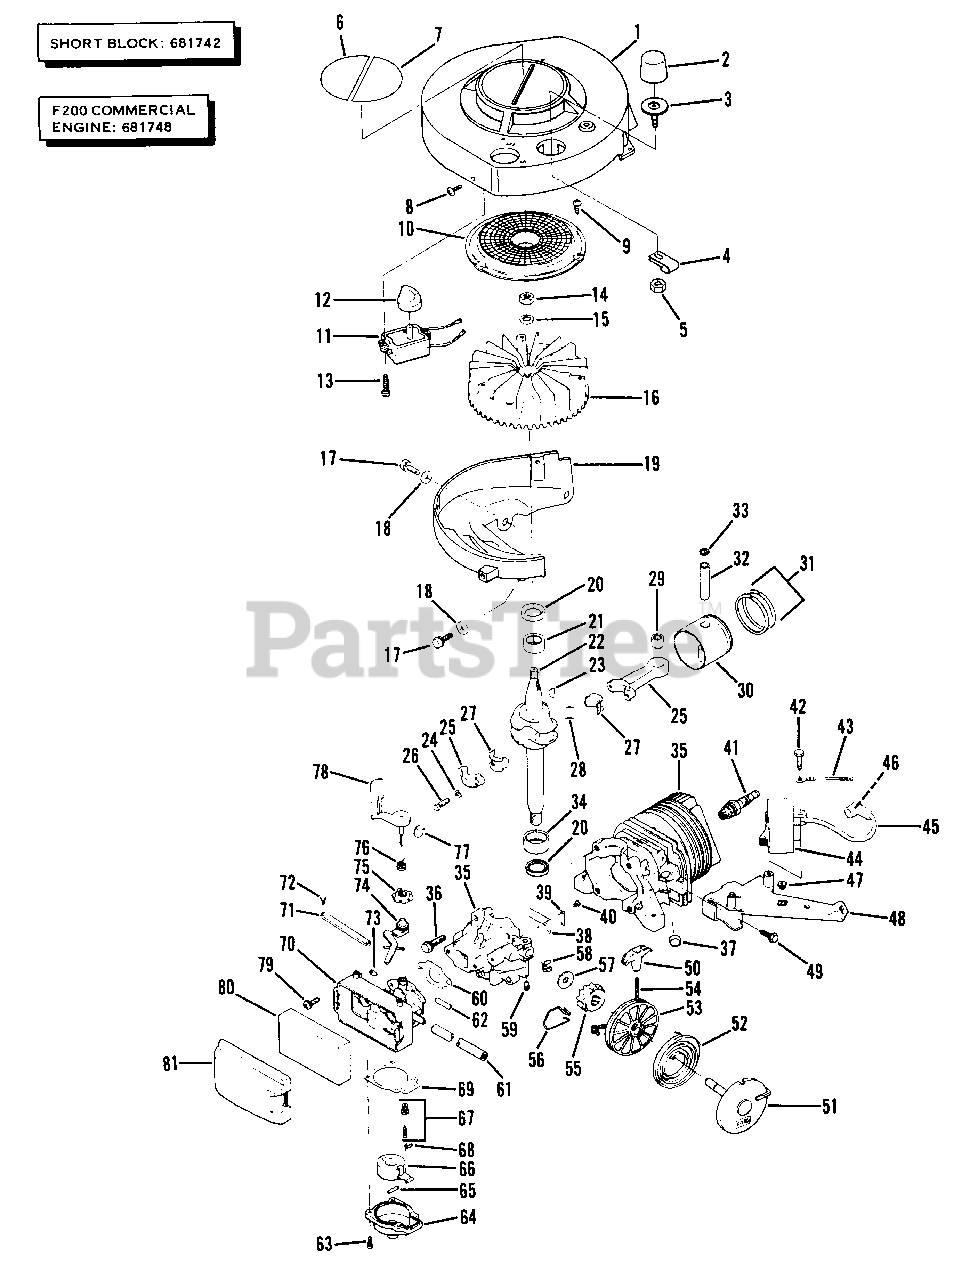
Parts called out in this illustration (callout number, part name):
1	Air Baffle, Primer & Decal Assembly
2	Bulb-Primer
3	Base-Primer
4	Clamp
5	Locknut-Primer
6	Decal-Fuel
7	Decal-Start
8	Screw-Baffle to Mount
9	Screw-Flywheel Screen
10	Screen-Flywheel
11	Switch Assembly
12	Knob
13	Screw
14	Nut-Flywheel
15	Lockwasher-Flywheel
16	Flywheel Assembly
17	Screw-Mount to Block
18	Washer
19	Mount-Air Baffle
20	Oil Seal
21	Bearing-Upper
22	Crankshaft
23	Key-Flywheel
24	Lockplate
25	Connecting Rod Assembly
26	Screw
27	Liner-Split
28	Needle Bearing Set
29	Bearing Assembly
30	Piston & Ring Set
31	Ring Set
32	Wrist Pin
33	Retaining Ring
34	Bearing-Lower
35	Cylinder & Crankcase Cover Assembly
36	Screw-Cover to Crankcase
37	Plug
38	Reed
39	Plate-Reed Hold Down
40	Screw-Reed to Crankcase Cover
41	Spark Plug
42	Screw-C.D. Mounting
43	Lead Assembly-Ignition
44	C.D. Ignition Module & Lead Assembly
45	High Tension Lead & Cover Assembly
46	Spring-Terminal
47	Grommet-C.D. Bracket
48	Bracket-C.D. Mounting
49	Screw
50	Handle-Starter
51	Cup & Pin Assembly
52	Spring
53	Pulley
54	Rope
55	Pinion
56	Spring
57	Washer
58	Retainer
59	Set Screw-Starter Assembly
60	Gasket-Carburetor to Crankcase Cover
61	Fuel Line
62	Tube-Primer
63	Screw-Float Chamber
64	Float Chamber
65	Pin-Float
66	Float
67	Float Valve & Seat Assembly
68	Clip
69	Gasket
70	Carburetor Body
71	Retainer-Speed Control Lever
72	Screw
73	Screw-Altitude Adjustment
74	Speed Control Lever
75	Collar
76	Spring
77	Disk-Throttle
78	Air Vane & Shaft
79	Screw-Carburetor Mounting
80	Element-Air Filter
81	Cover-Air Filter
